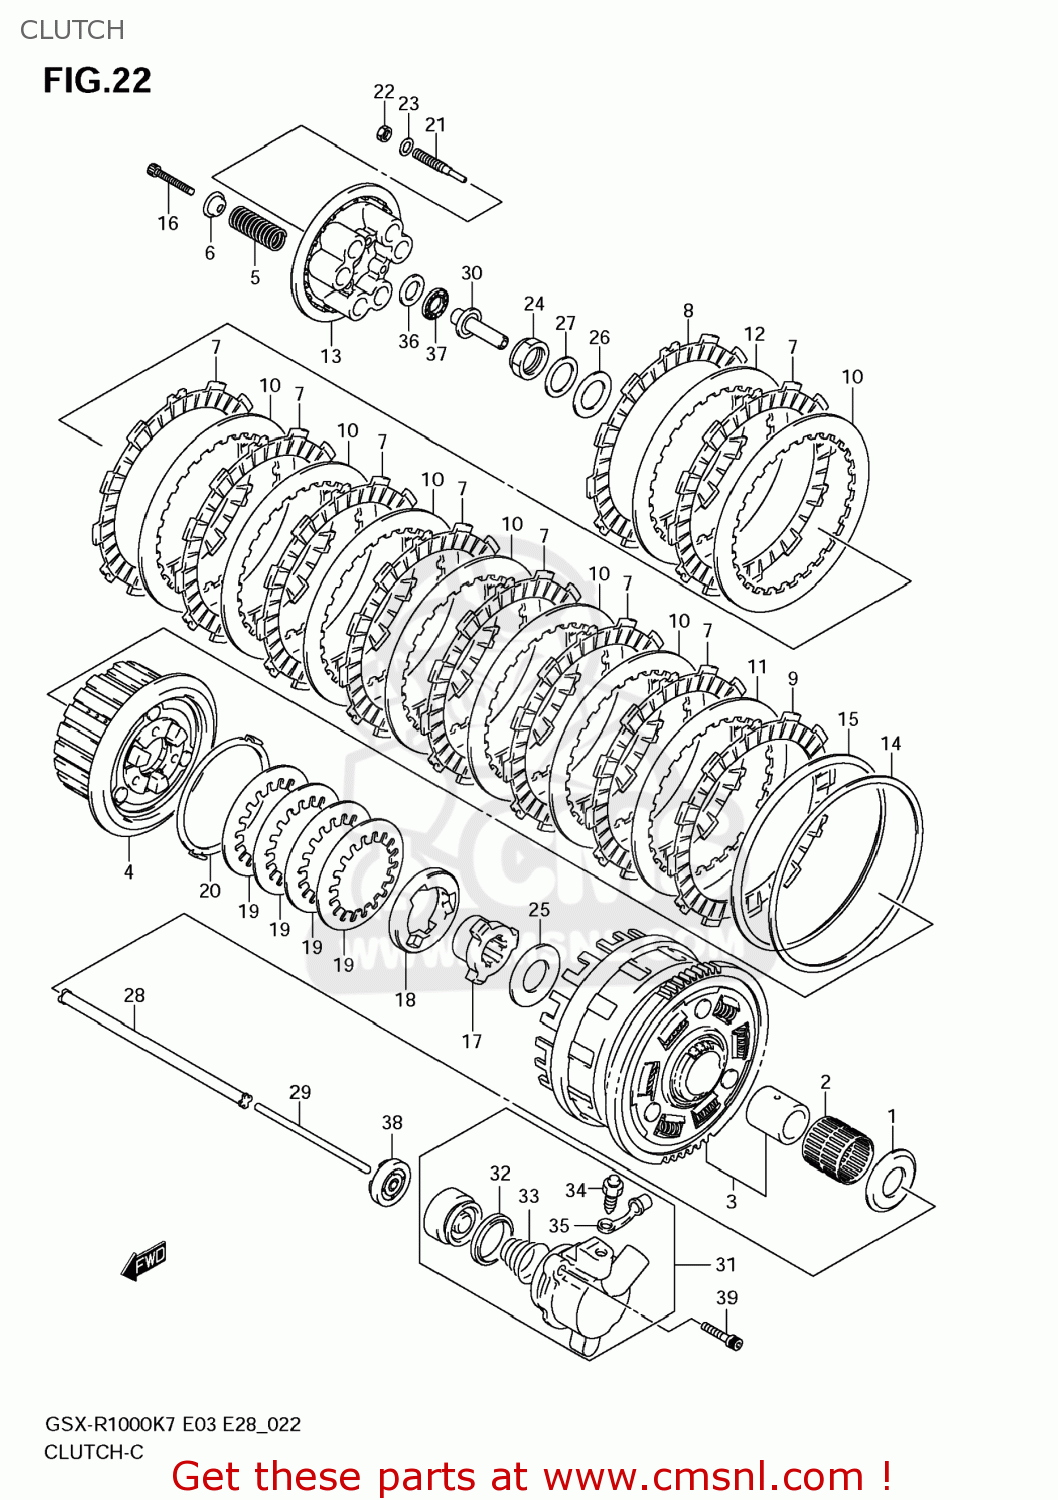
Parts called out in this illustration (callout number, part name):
1	WASHER(25X54X2.4)
2	BEARING(35X40X35.8)
3	GEAR ASSY,PRI DRIVEN
4	HUB,CLUTCH SLEEVE
5	SPRING,CLUTCH
6	WASHER
7	PLATE,CLUTCH DRIVE (NAS)
8	PLATE,CLUTCH DRIVE NO.2 (NAS)
9	PLATE,CLUTCH DRIVE NO.3 (NAS)
10	PLATE,CLUTCH DRIVEN(T:2.3) (NAS)
11	PLATE,CLUTCH DRIVEN NO.2 (NAS)
12	PLATE,CLUTCH DRIVEN (NAS)
13	DISC,CLUTCH PRESSURE
14	SEAT,WAVE WASHER
15	WASHER,CLUTCH PLATE WAVE
16	BOLT,CLUTCH SPRING
17	CAM,CLUTCH DRIVE
18	CAM,CLUTCH DRIVEN
19	WASHER,CAM REACTION WAVE
20	WASHER,CAM REACTION SEAT
21	LIFTER,CLUTCH PRESSURE DISC
22	NUT,CL PRESS DISC LIFTER LOCK
23	SHIM(8.8X14X1)
24	NUT
25	WASHER(25X50X2.5)
26	WASHER(25X41X2.5)
27	WASHER
28	ROD,CLUTCH
29	ROD,CLUTCH PUSH,L
30	PIECE,CLUTCH PUSH
31	CYLINDER,CLUTCH RELEASE
32	CUP
33	SPRING,CLUTCH CYLINDER
34	BLEEDER
35	CAP,BLEEDER
36	WASHER(15.5X28X1)
37	BEARING(15X28X2)
38	SEAL,OIL(6X34X10)
39	BOLT
